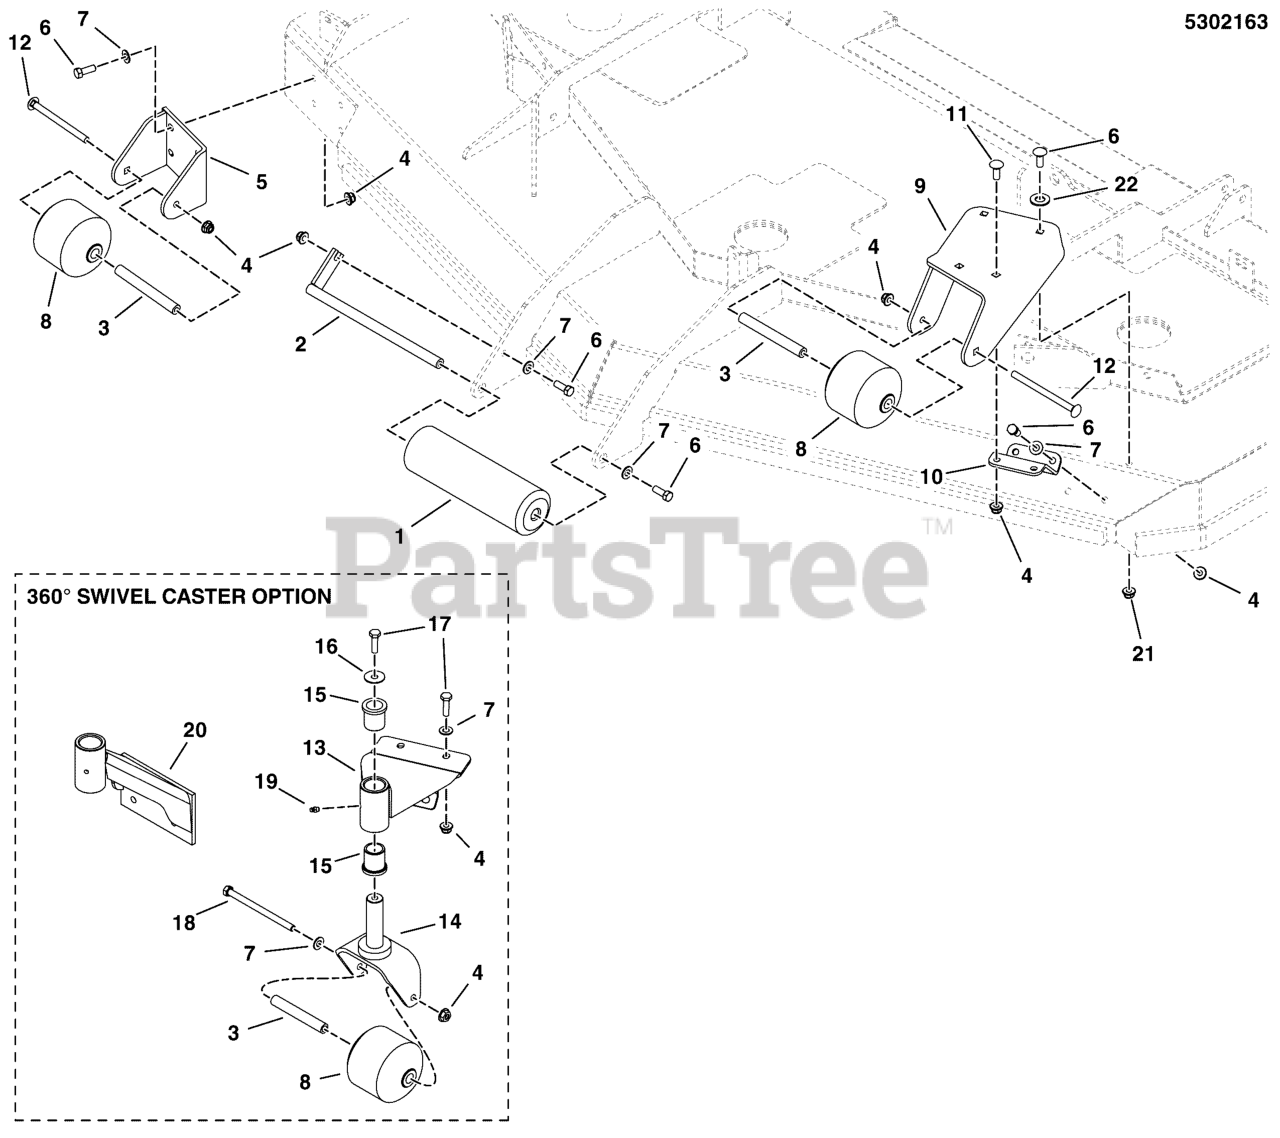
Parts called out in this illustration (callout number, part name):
1	ROLLER, DECK
3	SPACER, .38 X .63 X 4.31
4	NUT, 3/8-16 HEX NYLOCK FLANGE
5	BRACKET, ANTI-SCALP - RED
6	BOLT, 3/8-16 X 1" GD5 CZ
7	WASHER, 3/8 SAE
8	ROLLER, SMALL
9	WELD, ANTI-SCALP BRACKET
10	PLATE, ANTI-SCALP SUPPORT - RED
11	BOLT, RD HD SH SQ NK 3/8- 16X1.000 G5 BL
12	BOLT, 3/8-16 X 5-1/2, CARRIAGE
13	Swivel Caster Bracket
14	Caster Yoke
15	BUSHING, FLANGE
16	Washer, .390 X 1.50 X .109
17	BOLT, 3/8-16 X 3/4" GD5 CZ
18	BOLT, 3/8-16 X 5-1/2" GD5 CZ
19	Grease Fitting, 1/4-28 Straight
20	Anti-Scalp Caster Bracket
21	NUT, 3/8-16 HEX NYLON LOCK
22	WASHER, 3/8 GD.9 FLAT
